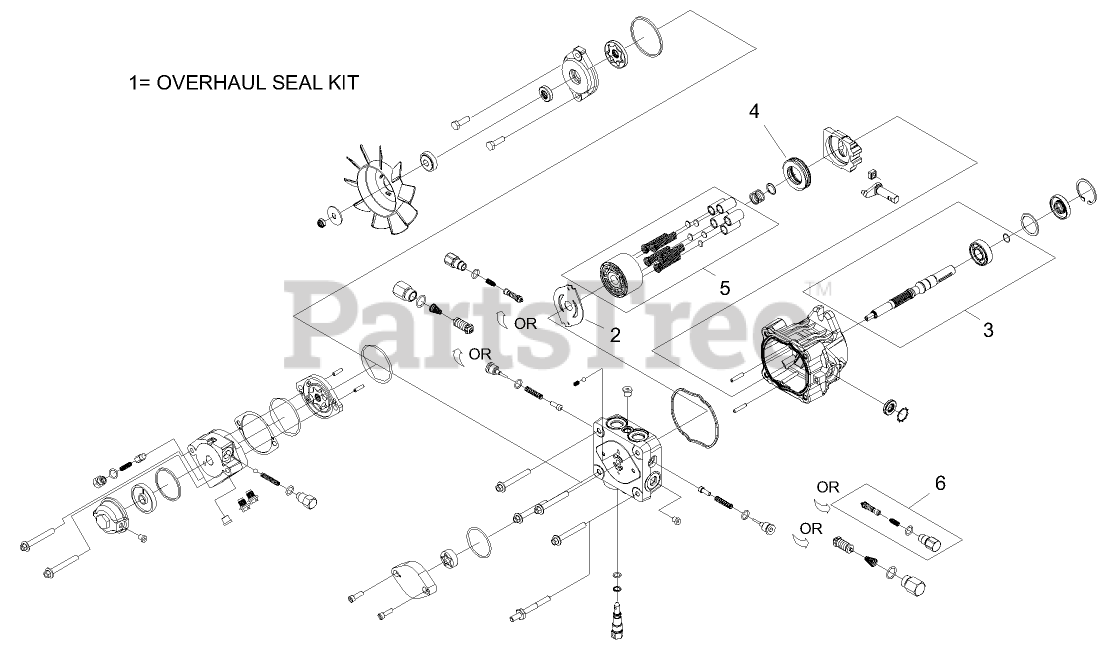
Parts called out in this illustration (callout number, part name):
1	SEAL OVERHAUL KIT
2	Plate-Valve
3	INPUT SHAFT KIT
4	BEARING-THRUST
5	CYLINDER BLOCK KIT
6	SHOCK VALVE KIT
